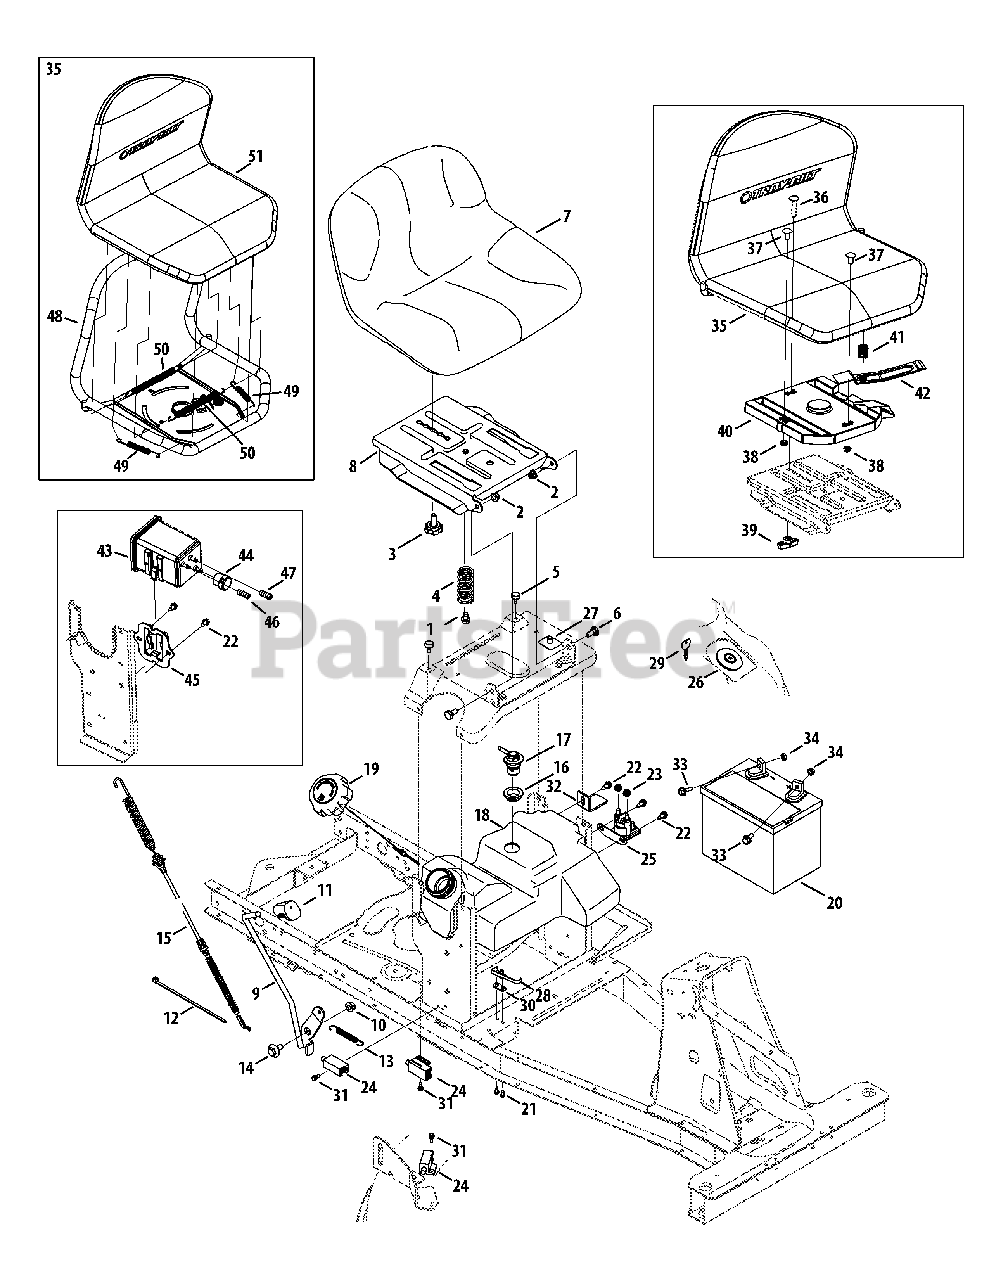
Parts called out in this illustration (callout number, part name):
1	Tap Screw, 5/16-18, 0.500
2	Flange Lock Nut, 5/16-18
3	Knob, 3/8-16, .875
4	Seat Spring
5	Bumper, .62 DIA X .3
6	Shldr Spacer, .435 X .178-5/16 X .56
7	Seat, Med Back Black
8	Seat Pivot Bracket
9	PTO Handle Assembly
10	Flange Lock Nut, 3/8-16
11	Handle Grip, 3/8
12	Cable Tie, 3/16 X .05 X 7.4
13	Extension Spring, .50 OD X 4.646 LG
14	Shoulder Bolt, .500 X .270 X 3/8-16
15	PTO Cable
16	Rubber Grommet
17	Rollover Valve
18	Fuel Tank, 1-3 Gal.
18	Fuel Tank, 1.3 Gal., Carb
19	Fuel Cap
19	Fuel Cap, Carb
20	Battery, 155 CCA
21	Screw, #8
22	Tap Screw, 1/4-20, .625
23	Flange Lock Nut, 1/4-20
24	Interlock Switch
25	Solienoid, 12v
26	Three-Way Key Switch
27	Seat Switch
28	Switch Spring
30	Insulator Plate
31	Shoulder Screw, #10-32, .500
32	Battery Hold-Down Bracket
33	Screw, Shoulder, .250 x .150
34	Nut, Sems, 1/4-20
35	Seat (TB) Mesh
36	Carriage Bolt, 3/8-16 x 1.75
37	Carriage Bolt, 3/8-16 x .75
38	Nut, Jam, 3/8-16
39	Wing Knob, 3/8-16
40	Seat Pan Support
41	Compression Spring, .845 OD x 1.00
42	Seat Bracket
43	5 Gallon Carbon Canister
44	Vent Filter Canister
45	Canister Adapter Bracket
46	Fuel Hose, White
47	Fuel Hose, Yellow
50	Extension Spring, 7.91 LG
51	Seat Cover
